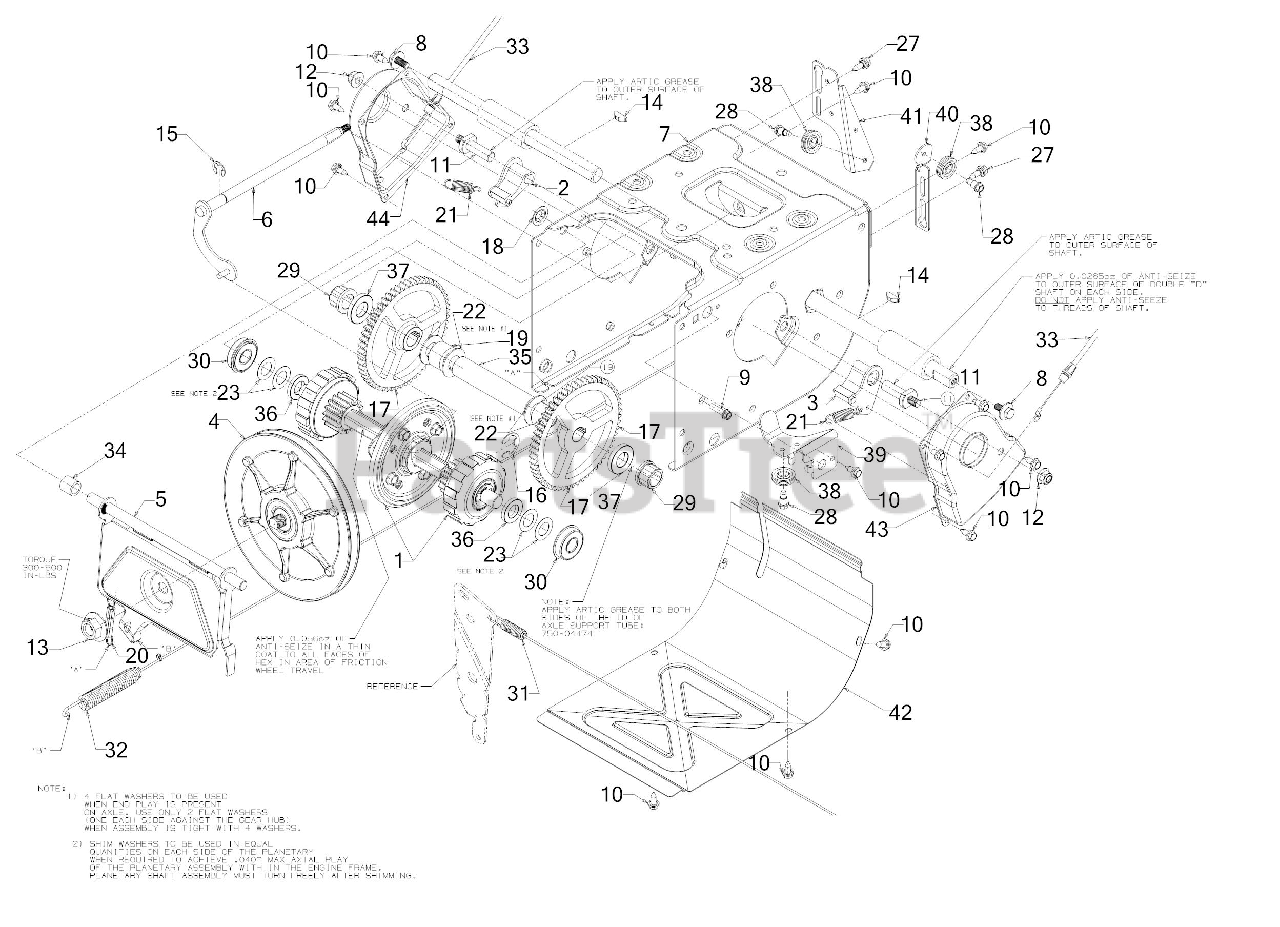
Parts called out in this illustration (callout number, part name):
1	PLANETARY SHIFT ASSEMBLY
1	PLANETARY CARRIER
1	FRICTION WHEEL ASSEMBLY
2	DOGG ASSEMBLY (RH)
3	DOGG ASSEMBLY (LH)
4	FRICTION WHEEL DISC ASSEMBLY
5	FRICTION WHEEL BRACKET
6	SHIFT ROD ASSEMBLY
7	DRIVE FRAME HOUSING
8	SCREW 5/16-24 x .750 GR5
9	SCREW 1/4-20 x 1.00
10	SCREW 1/4-20X.625
11	ACTUATOR SHAFT
13	FLANGE NUT 5/8-18
14	KEY 3/16 x 3/4
15	E-RING FOR .500
16	RETAINING RING
19	SPACER: .76ID x .75
20	EXTENSION SPRING
21	EXTENSION SPRING
22	FLAT WASHER .760ID X1.49OD x .06
23	FLAT WASHER .67X 1.174X .02
27	SHOULDER SCREW
28	SHOULDER SCREW
29	FLANGE BEARING
30	BALL BEARING
31	AUGER DRIVE CABLE 47.48"
32	WHEEL DRIVE CABLE 44.955"
32	EXTENSION SPRING
33	STEERING CABLE
34	SPACER-.513 ID x .703 OD x .69
35	AXLE SUPPORT TUBE
37	AXLE SPACER
38	CABLE GUIDE ROLLER
39	AUGER CABLE BRACKET
40	AUGER CABLE GUIDE BRACKET
41	GUIDE BRACKET
43	STEERABLE DRIVE SHAFT RETAINER (LH)
44	STEERABLE DRIVE SHAFT RETAINER (RH)
